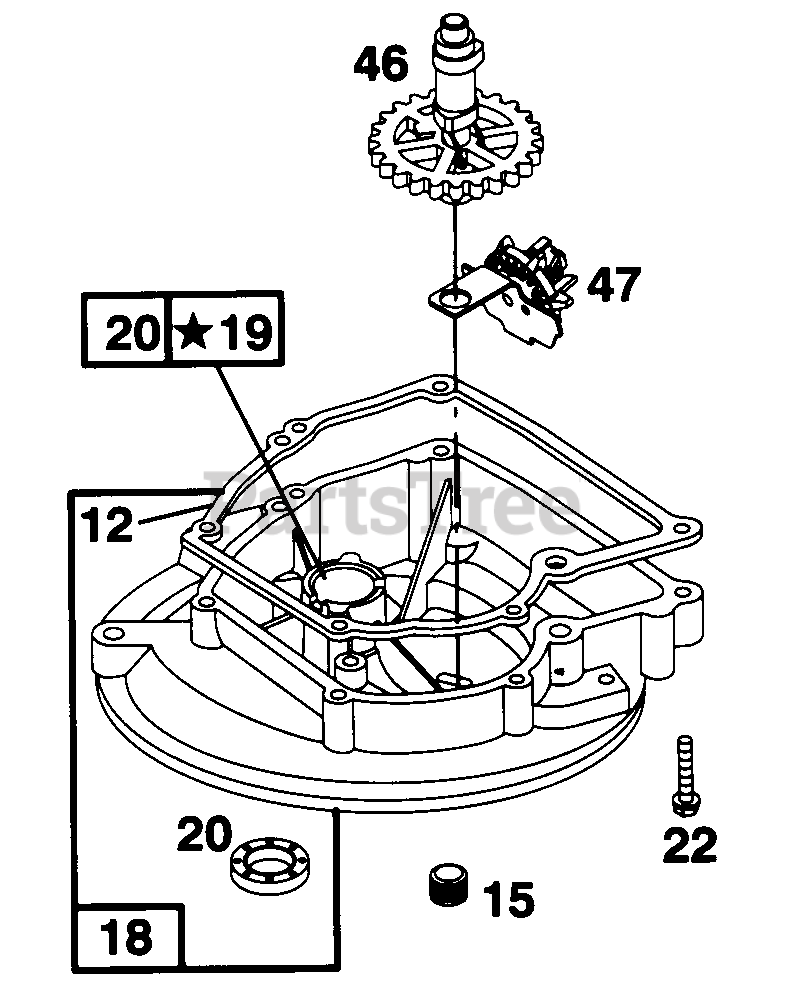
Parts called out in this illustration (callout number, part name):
12	Gasket-Crankcase (.015" Thick, Standard)
15	Plug-Oil Drain
18	Sump-Engine
20	Seal-Oil
22	Screw-Mtg. Sem
47	Slinger-Oil
